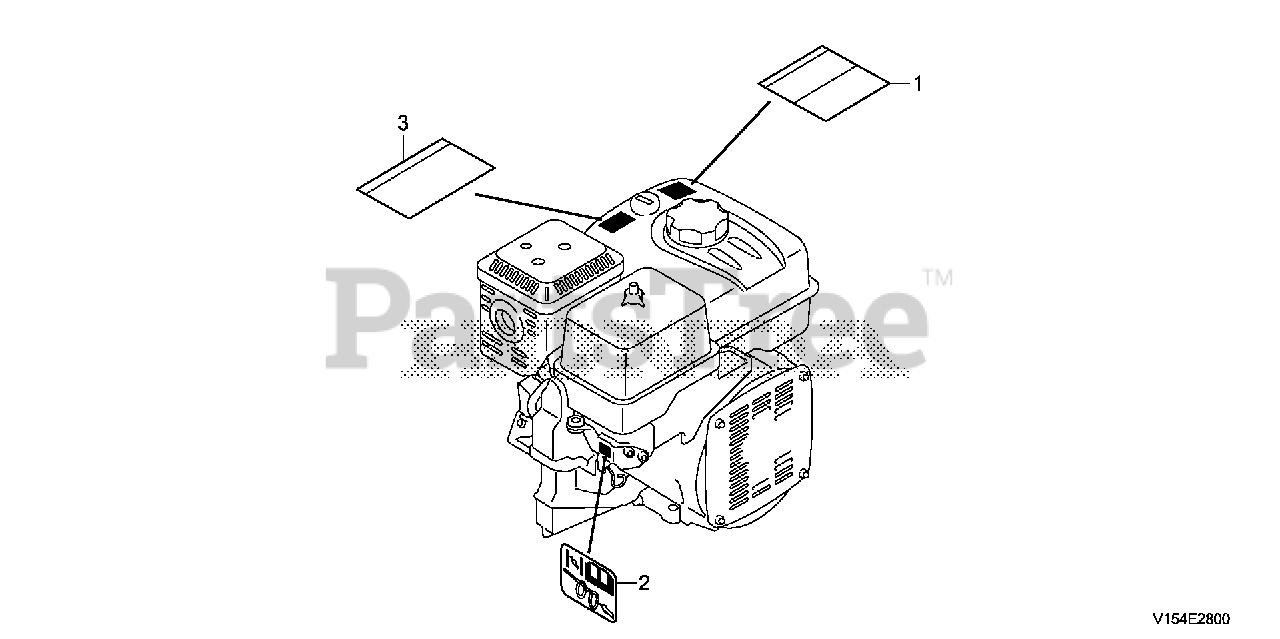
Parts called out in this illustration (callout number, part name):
1	MARK, FUEL WARNING COMBINATION (ENGLISH)
2	MARK, CHOKE
3	MARK, EX. CAUTION (ENGLISH)
